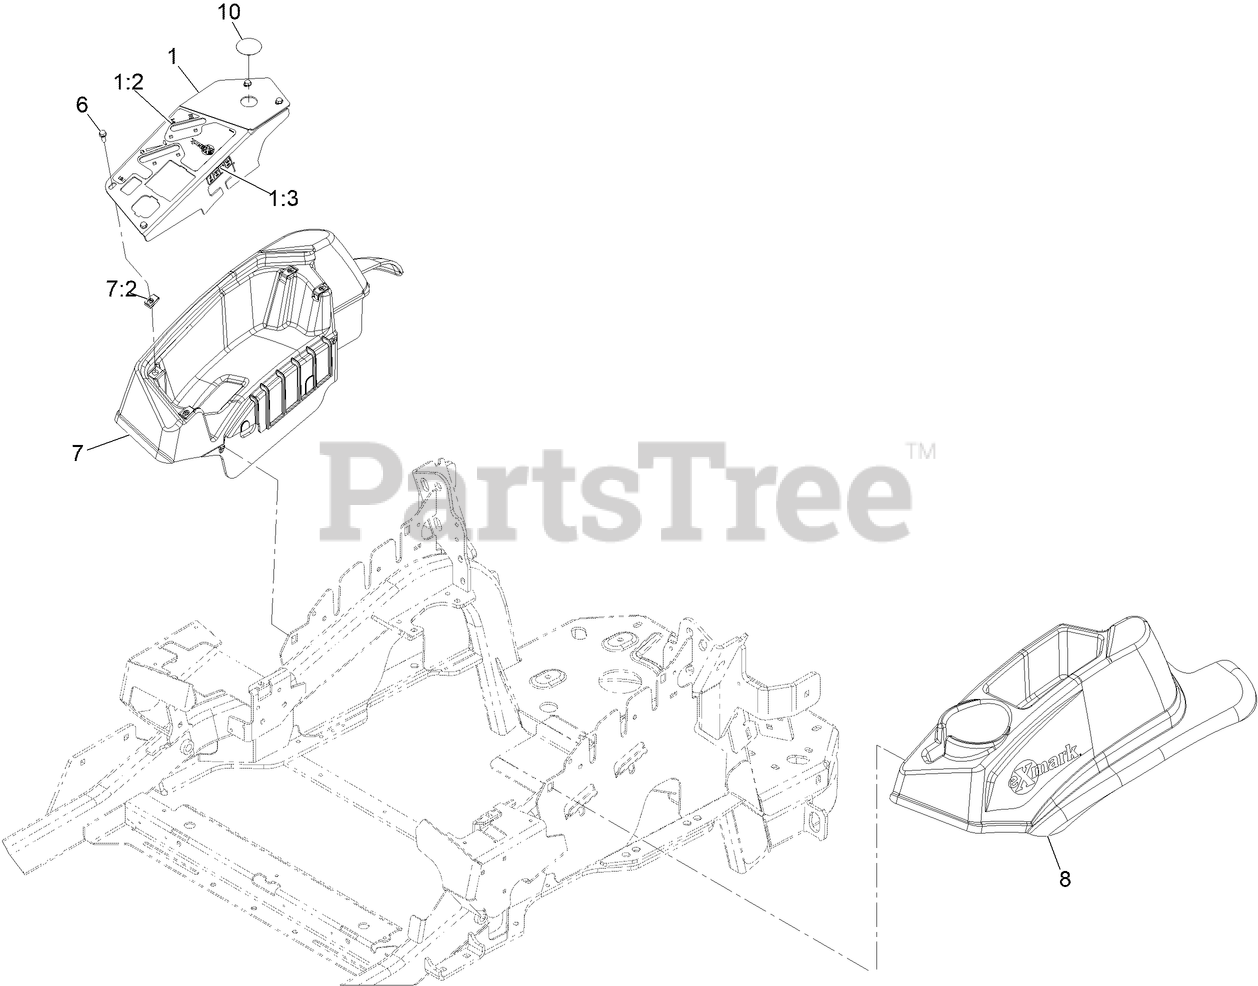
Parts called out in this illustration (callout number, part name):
1	CONSOLE,PANEL W/DECAL
1:2	DECAL-CONTROL PANEL NON-EFI
1:3	DECAL-FUSES
6	SCREW-HWH
7	ASM - RH Console
8	Console-LH
10	Decal-Cover 12V
